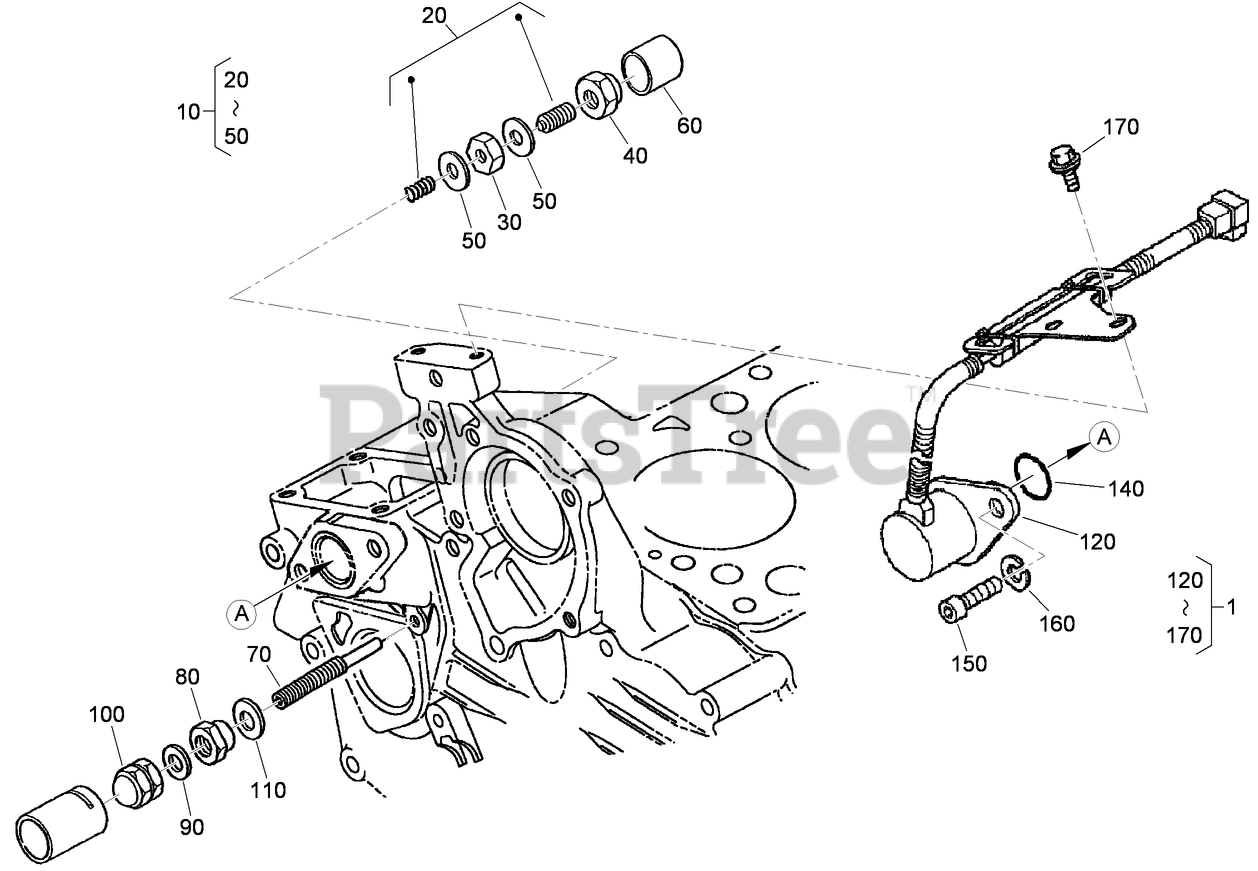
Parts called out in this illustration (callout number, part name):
1	OBS SOLENOID ASM
10	IDLE APPARATUS ASM
20	ADJUSTING BOLT ASM
40	NUT-CAP
50	GASKET
70	BOLT-ADJUSTING
80	NUT-LOCK
90	GASKET
100	NUT-CAP
110	GASKET
120	SOLENOID STOP ASM
140	O-RING
150	BOLT-HSH
160	WASHER-SPRING
170	BOLT-FLANGE
